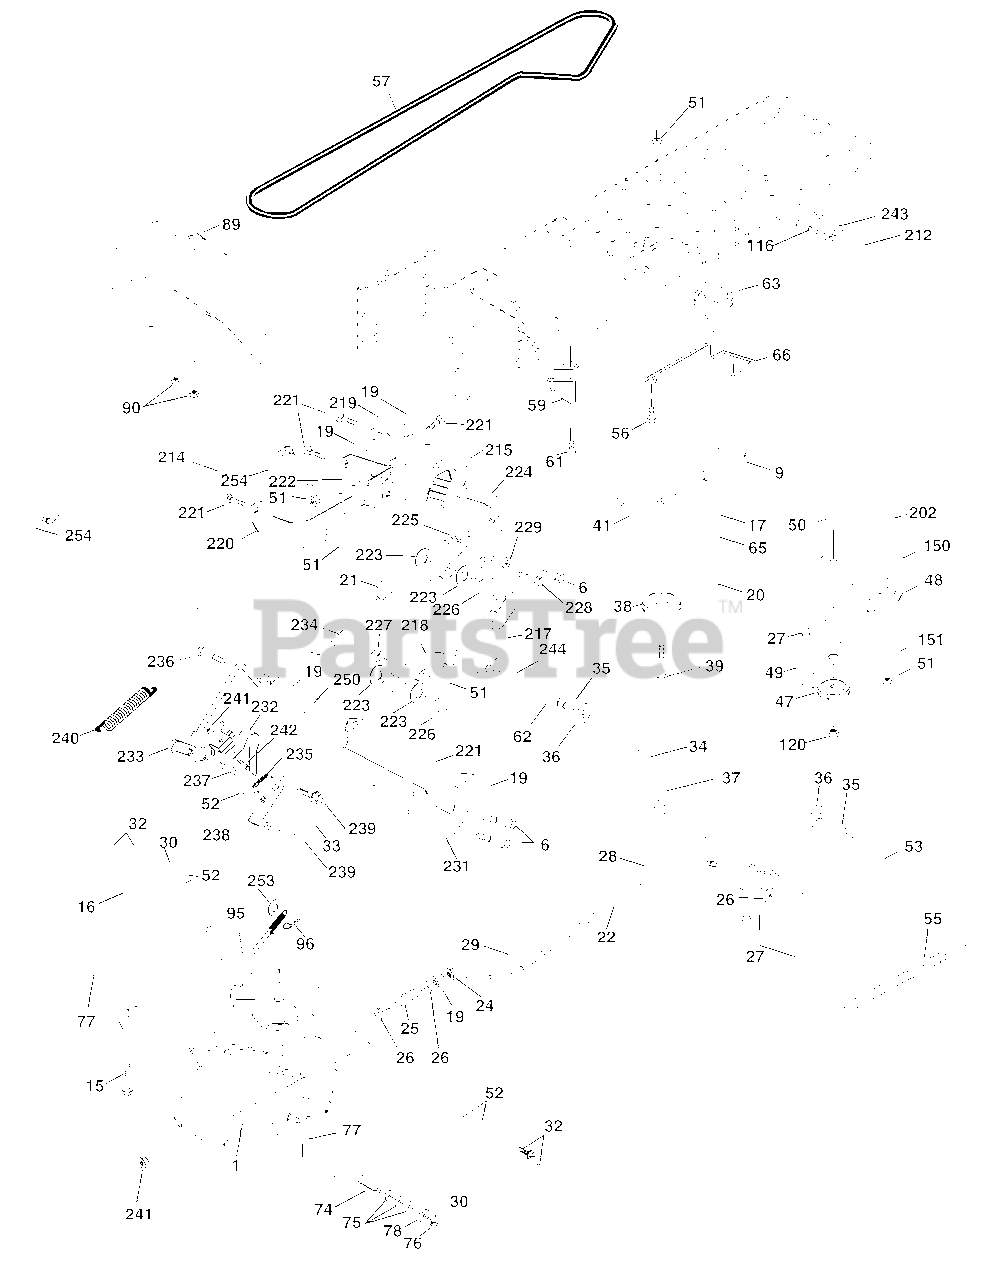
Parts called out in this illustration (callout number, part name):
6	Screw 5/16-18 x 3/4
9	Clutch Elec
15	Bolt Hex Flghd 5/16-18 Gr. 5
16	Nut Lock Hex W/Ins. 5/16-18 Unc
17	Washer 1-1/2 OD x 15/32 ID x .250
19	Nut Lock Hex W/Wsh 3/8-16 Unc
20	Bolt Hex 7/16-20 x 4-1/4 x Gr. 5
21	Knob Custom Control Cruise
22	Rod, Brake
24	Nut, Hex Jam 3/8-16 Unc
25	Spring, Brake Rod
26	Washer
27	Pin Cotter 1/8 x 3/4 CAD.
28	Rod, Parking Brake
29	Cap, Brake, Park
30	Bracket, Transaxle
32	Bolt Hex Hd 5/16-18 Unc x 3/4
33	Bolt Rdhd Sqnk 5/16-18 Unc x 3/4
34	Shaft, Foot Pedal
35	Bearing, Nylon
36	Washer
37	Pin, Roll
38	Pulley, Composite, Flat
39	Bolt Fin Hex 3/8-16 Unc x 3
41	Keeper, Belt Idler Flat
47	Pulley, Idler, V-Groove
48	Bellcrank Clutch Grnd Drw Stl
49	Retainer, Belt
50	Bolt
51	Nut Crownlock 3/8-16 UNC
52	Nut, Crownlock 5/16-18 Unc
53	Link, Clutch
55	Spring, Return, Clutch
56	Screw 3/8-16 x 1.0
57	V-Belt, Ground Drive
59	Keeper, Center Span
61	Screw 3/8-16 x .875
62	Cover, Pedal
63	Pulley, Engine
65	Washer
66	Keeper Belt Engine
74	Spacer, Axle
75	Washer 25/32 x 1-1/4 x 16 Ga.
76	E-Ring
77	Key, Square
78	Washer 25/32 x 1-5/8 x 16 Ga.
89	Console, Shift
90	Nut Self-Thd Wsh-hd 1/4 Zinc
95	Rod Bypass
96	Retainer Spring 1" Zinc/Cad
116	Bolt RDHD SQNK 3/8-16 Unc x 1
120	Nut Lock Flg 3/8-16 Unc
150	Spacer Retainer
151	Washer 13/32 x 2 x 10 Ga.
202	Bolt Carr Sh 3/8-16 x 1-1/2 Gr. 5
212	Nut Hex Flange Lock
214	Link Transaxle
215	Cover Pedal Forward
217	Pedal Reverse
218	Arm Control Pedal Reverse
219	Bracket Frest Pdl Ctrl. Hyd
220	Bracket Mtg. Pedal Control
221	Bolt Rdhd Sqnk 3/8-16 Unc x 3/4
222	Nut Crownlock 7/16-14 Unc
223	Washer Nylon 11/16 ID x .060
224	Pedal Forward
225	Arm Control Pedal Forward
226	Bolt Pivot Spacer
227	Cam Reverse Pedal LT
228	Bolt Shoulder 5/16-18
229	Washer Serrated 5/16 x .75
231	Strap Torque
232	Actuator Cruise Disengage
233	Pawl Control Cruise
234	Lever Control Cruise
235	Sector Control Cruise
236	Bolt Shoulder 3/8-16 Unc 1/44
237	Bolt Shoulder 5/16-18
238	Arm Mtg. Cruise Sector
239	Screw Thdrol 5/16 x 1/2
240	Spring Return Cruise Control
241	Nut Centerlock 1/4-20 Unc
242	Bolt Fin Hex 1/4-20 Unc x .75
243	Bracket Anti-Rotation CVX
244	Screw 5/16-18 x 5/8
250	Screw 3/8-16 x .75
253	Washer .3125 x .615 x 16 Ga.
254	Clip Retainer
